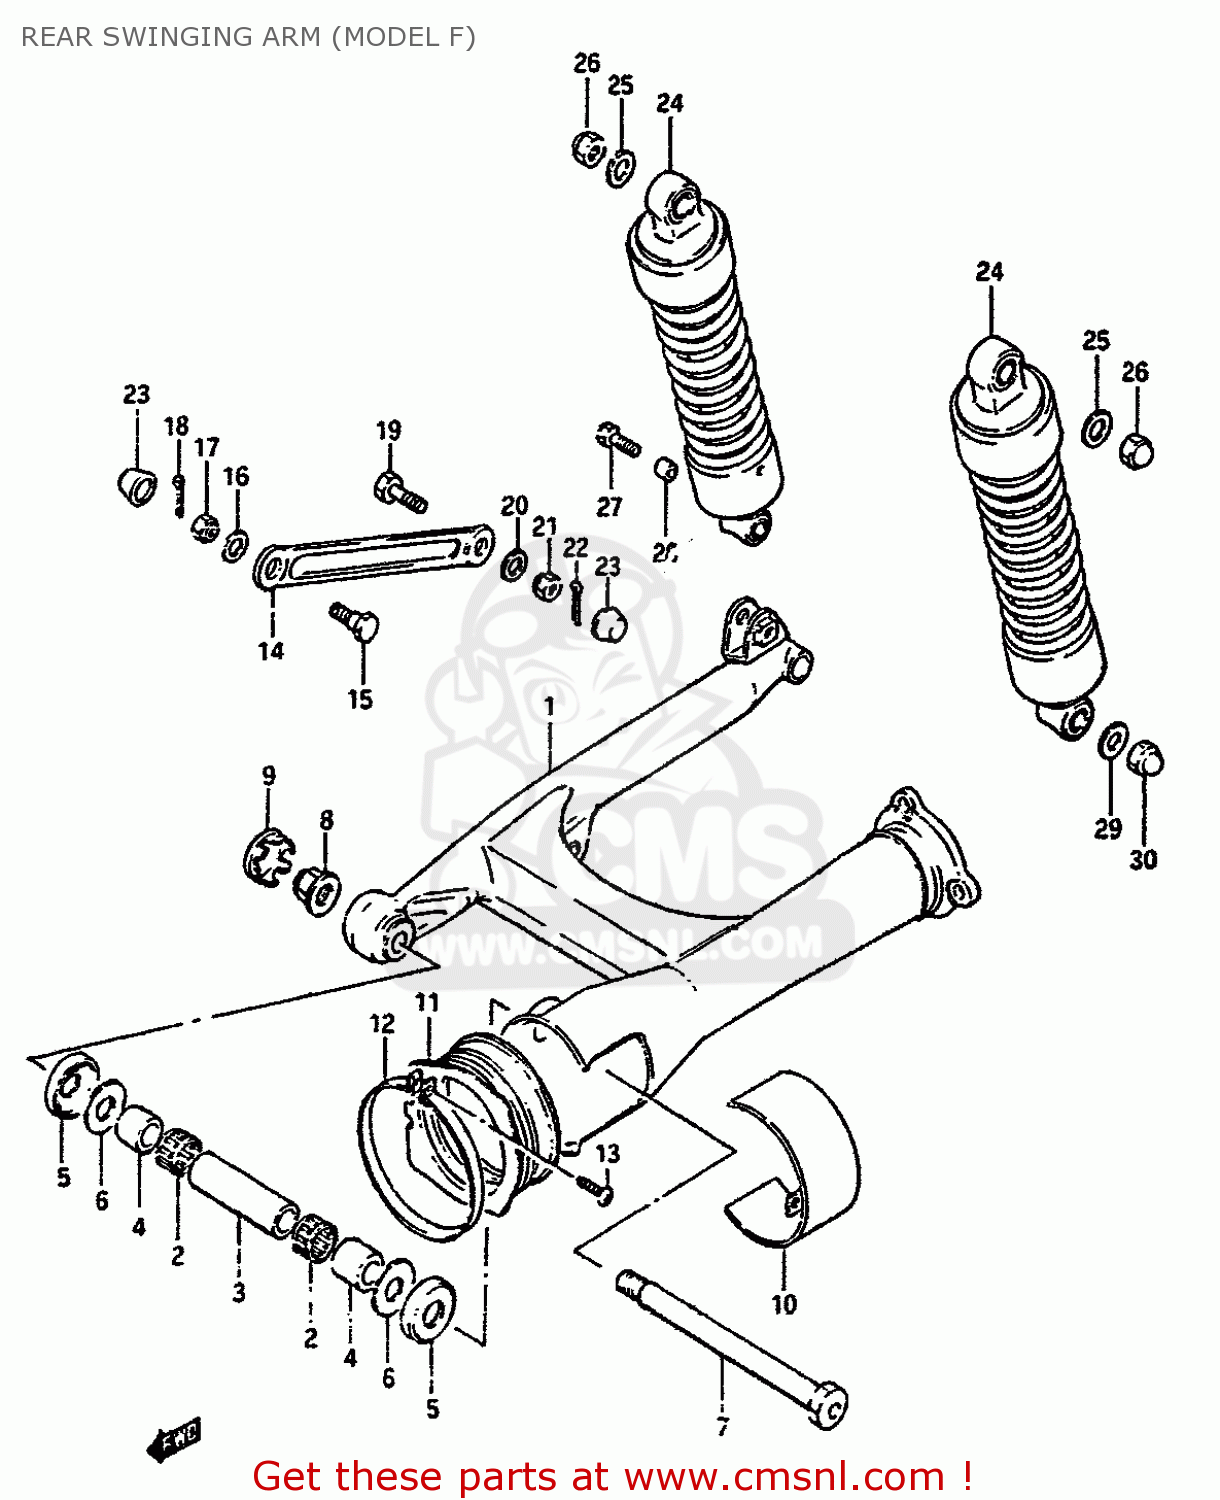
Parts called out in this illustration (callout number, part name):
1	SWING ARM ASSEMBLY,REAR
2	BEARING(22X29X20)
3	SPACER,REAR SWING ARM PIVOT
4	SPACER,RR SWGARM PIVOT
5	CVR,RR SWGARM DUST SEAL(OD:40)
6	WASHER
7	SHAFT,RR SWINGINGARM PIVOT
8	NUT
9	CAP,RR SWINGING ARM PIVOT,R
10	COVER,REAR SWING ARM PIVOT
11	BOOT,PROPELLER SHAFT
12	CLAMP
13	SCREW
14	TORQUE LINK,REAR
15	BOLT(10X24.5)
16	WASHER (10.5X18X1)
17	NUT
18	COTTER PIN
19	BOLT 10X35
20	WASHER (10.5X18X1)
21	NUT
22	COTTER PIN
23	CAP
24	ABSORBER ASSEMBLY,REAR SHOCK
25	WASHER
26	NUT
27	BOLT(10X36)
28	SPACER (10.2X14X20.7)
29	WASHER
30	NUT
